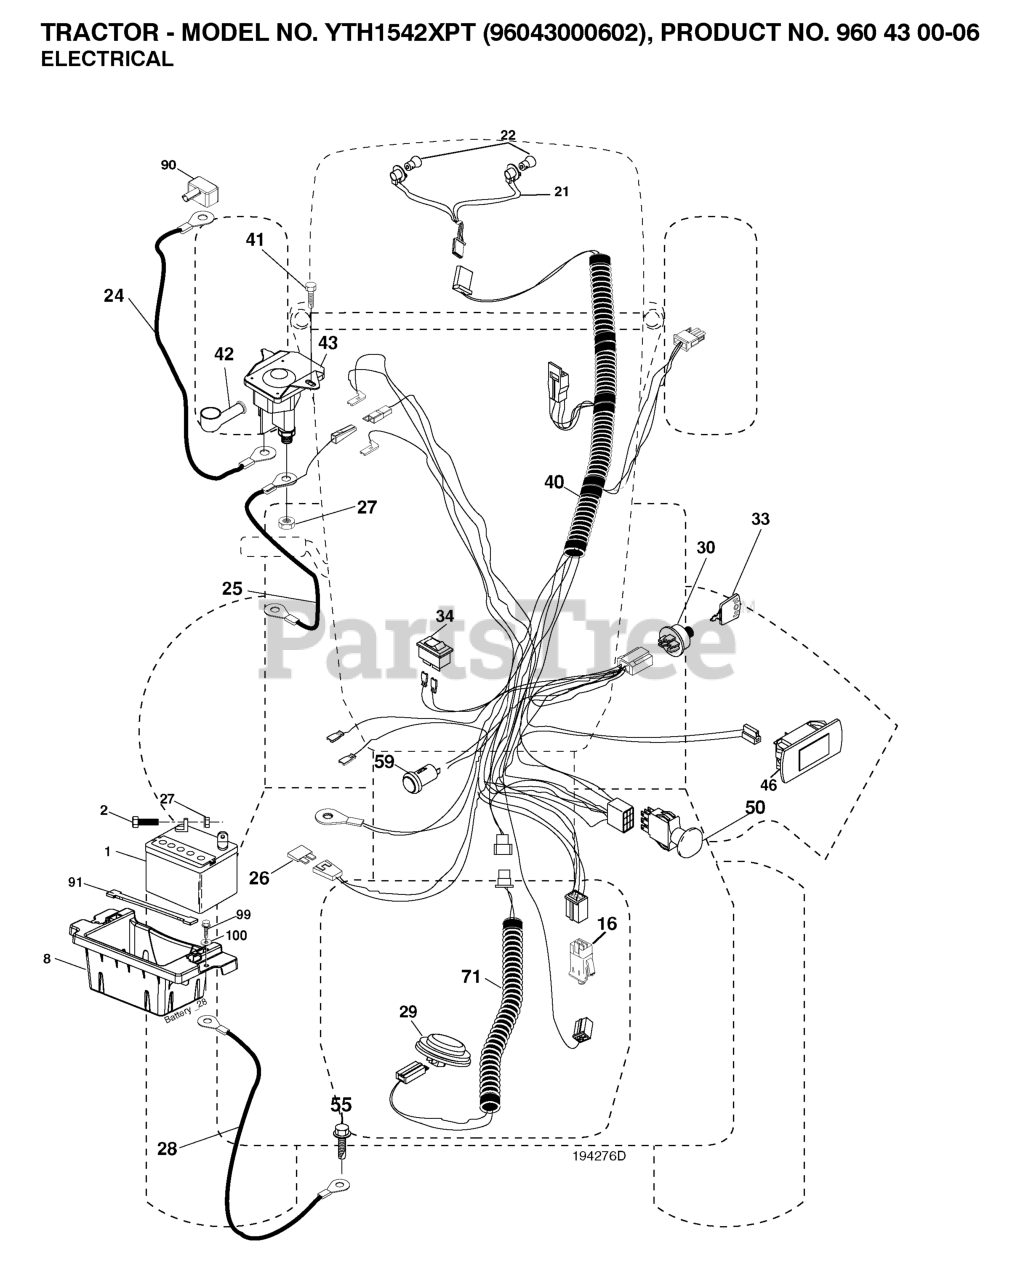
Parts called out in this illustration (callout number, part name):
1	BATTERY 12V .35 AMP
2	BOLT.HEX.1/4.X.3/4.DICHROMATE
8	BOX.BATTERY.MOUNT.FRONT.LT
16	SWITCH INTERLOOK PUSH-IN
21	HARNESS ASSY LIGHT
24	CABLE.BATT.POS.WIRE.TG.DA SOL
25	CABLE.START.RED.17.5".
26	FUSE 20AMP
27	NUT
28	CABLE GROUND 6 GA 21" 90T BLK
29	SWITCH.SEAT.DELTA.OPC.
30	SWITCH.IGN.DELTA.W.LGH.ROS
33	KEY MLD GEN DELTA
40	HARNESS-CHASSIS SUB
41	SCREW
42	TERMINAL COVER
43	SOLENOID.W/BRASS.PLUNGER
46	GAUGE.SERVICEMINDER.HR
50	RP.PTO.SWITCH.8 TERMINAL.BLACK
55	SCREW.THDROL.5/16-18X3/4.TTY
59	OUTLET.12-VOLT
71	HARNESS.IGN.DASH.HUQ/PRED.OUTL
90	COVER.TERMINAL.BATTERY
91	STRAP.BATTERY.MOUNT.FRONT(2 2)
99	SCREW HEXWSHR 1/4-20X3/4
